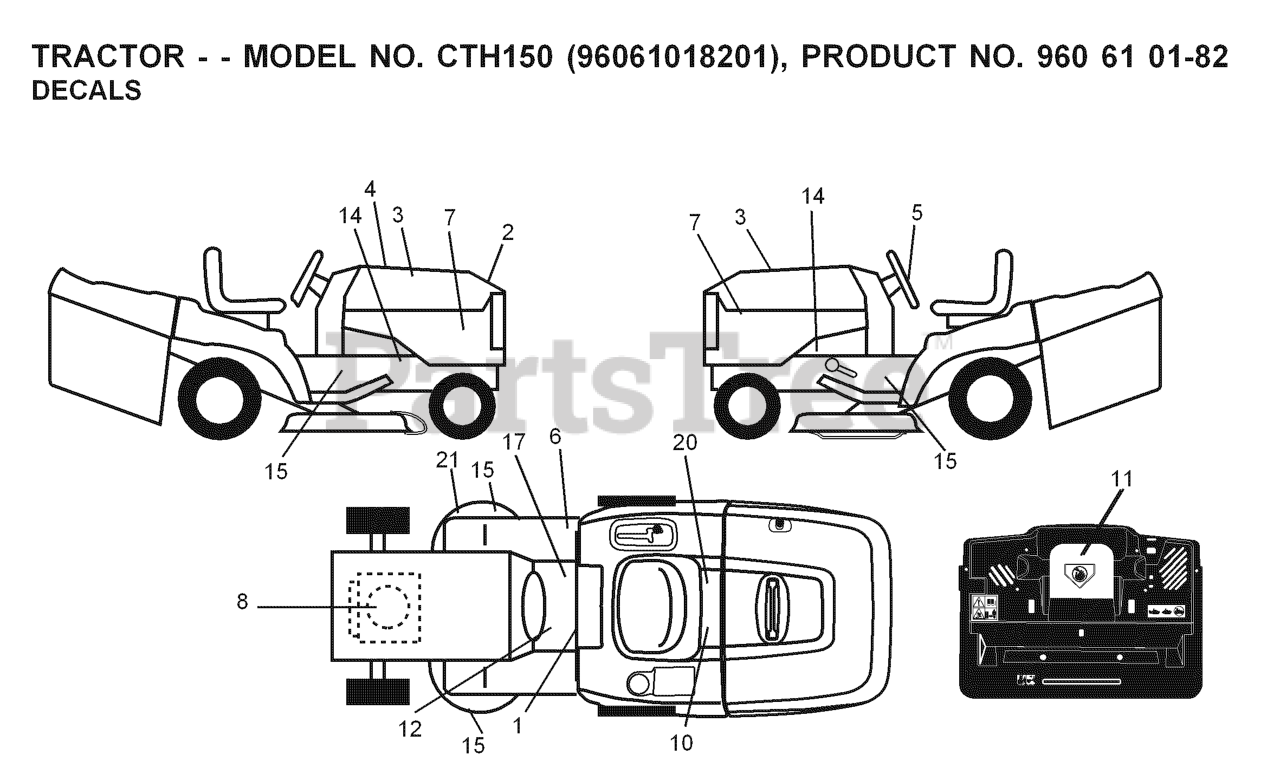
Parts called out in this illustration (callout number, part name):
1	LABEL
2	DECAL.HOOD.TOP.INSERT.
3	DECAL.HOOD.NAMELOGO.HUSQ
5	DECAL.WHEEL.STRG.LGN.H
6	Decal, Fender 100 DB/CE
8	DECAL
10	DECAL BTRY SYMBOLS
11	DECAL.INTERNATIONL.CUTFINGER
12	DECAL
17	DECAL PARK BRAKE
20	DECAL.BYPASS.FENDER.CRD.LT.YT
